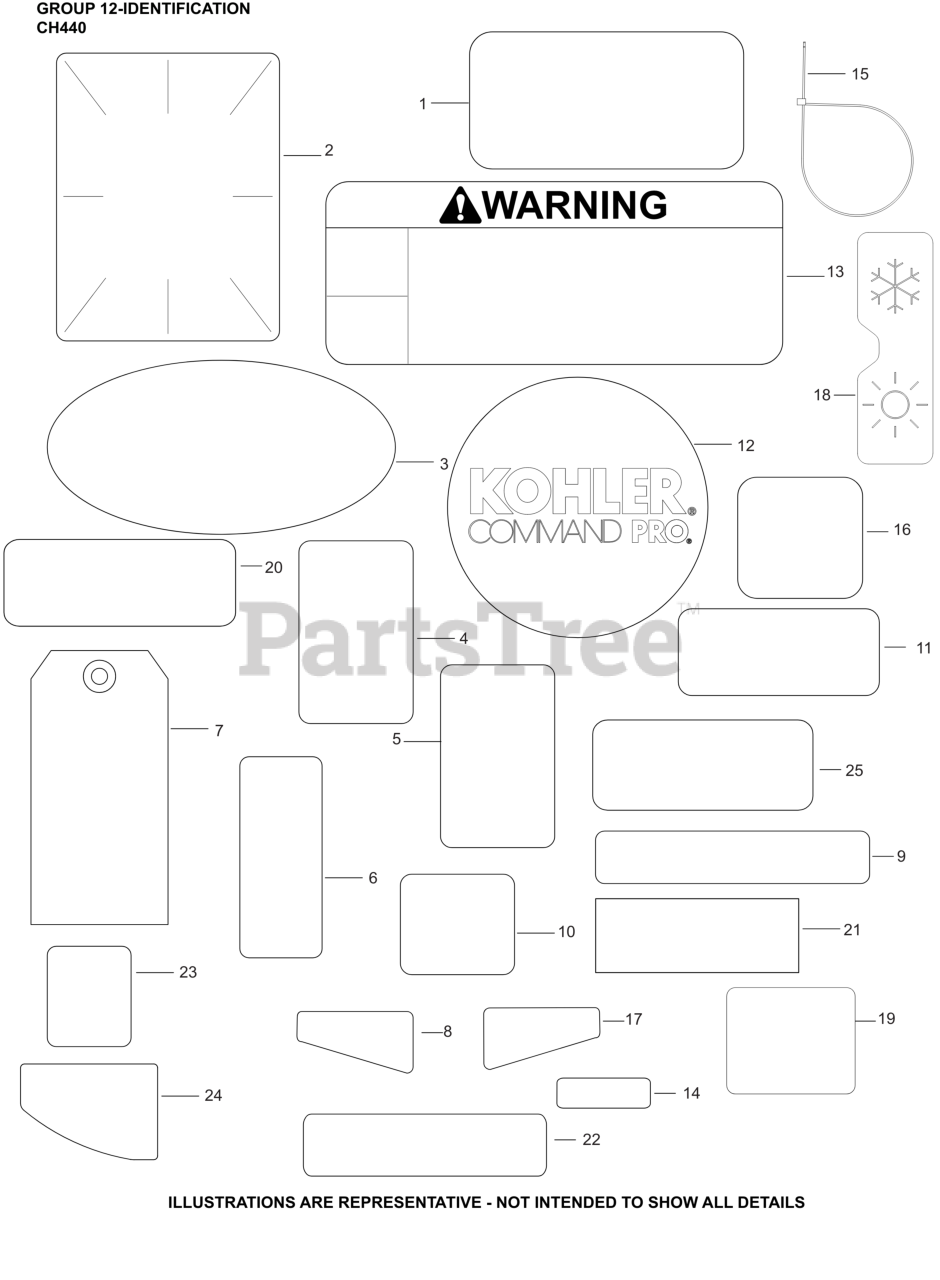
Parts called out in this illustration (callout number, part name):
1	LABEL, MAINTENANCE (CKY)
2	LABEL, CLEAR LAMINATION
3	DECAL, QUAD CLEAN SILVER
4	DECAL, SNOW FLAKE
5	DECAL, SUN
6	DECAL, FUEL/CHOKE - ON/OFF
8	DECAL, 14 HP/429cc/CH440
9	DECAL, THROTTLE
10	DECAL, BASE ARROW
11	LABEL, CANADIAN COMPLIANCE
11	DECAL, ETHANOL WARNING
12	LABEL, RECOIL 75MM
13	DECAL, WARNING
